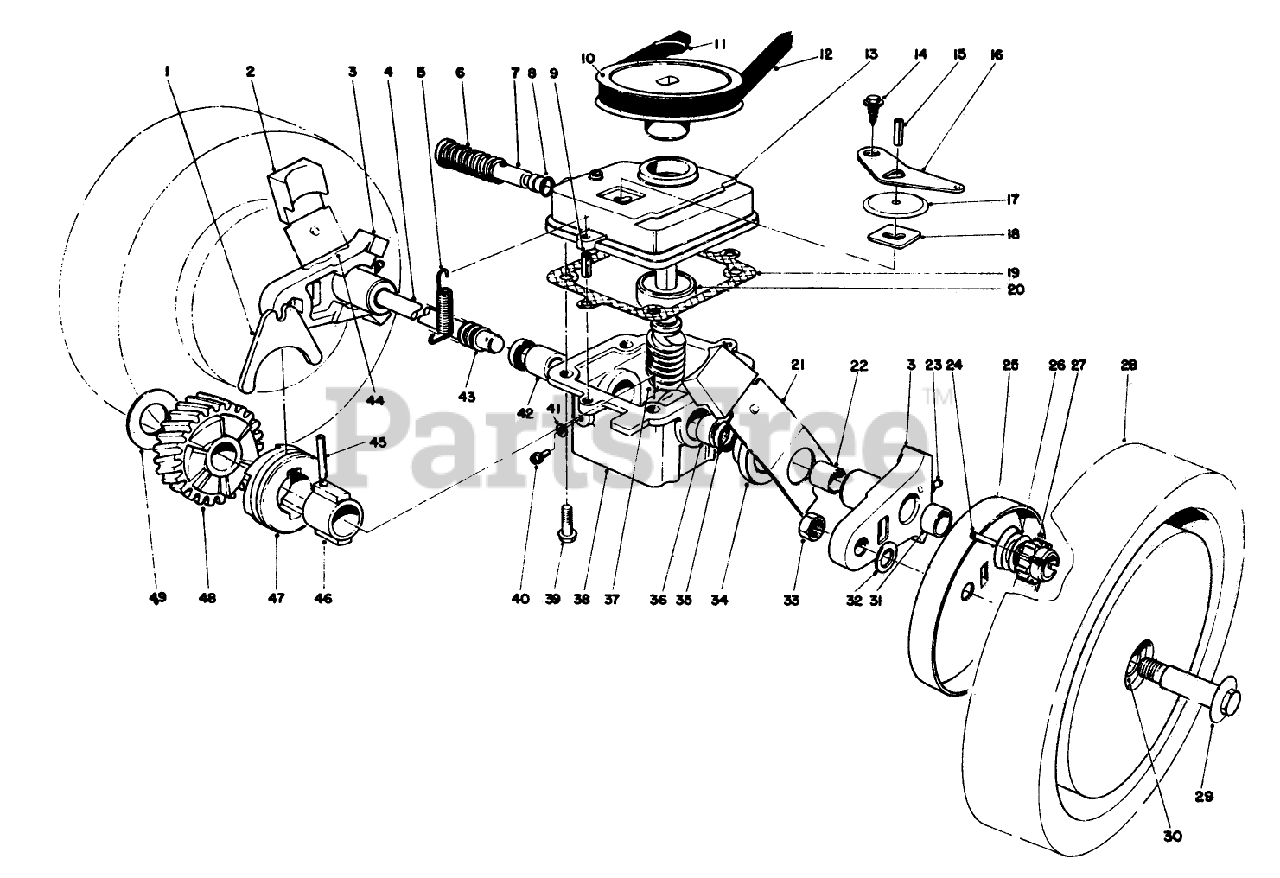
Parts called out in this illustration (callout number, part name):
1	SHIFTER FORK
2	KNOB-ARM
3	PIVOT ARM ASM
4	DRIVE SHAFT (SERVCE)
5	TENSION SPRING
6	SPRING
7	SHIFTER ROD
8	O-RING
9	3/16 X 1/2 ROLL PIN
10	PULLEY
11	PUSH-ON 93-3236
12	BELT-V
15	PIN-ROLL
16	SHIFTER ARM
17	TRANS DUST COVER
18	LATCH PLATE
19	GASKET
20	BEARING - BALL
22	BUSHING
23	FITTING-GREASE
25	WHEEL COVER
27	PINION GEAR 14T
28	WHEEL-TIRE ASM SERVICE
29	WHEEL BOLT
30	BUSHING
31	BUSHING
32	WASHER
33	NUT-LOCK
34	CAP-END
35	SEAL-OIL
36	BUSHING
37	WORM SHAFT & GEAR SET
38	GEAR CASE ASM
40	NYLON SCREW
41	FILL PLUG GASKET
42	BUSHING
43	COVER-SHAFT, DRIVE
44	SPRING ARM ASM SP RH
45	COIL PIN
46	SLEEVE
47	CLUTCH JAW
48	Helical Gear
49	THRUST WASHER
